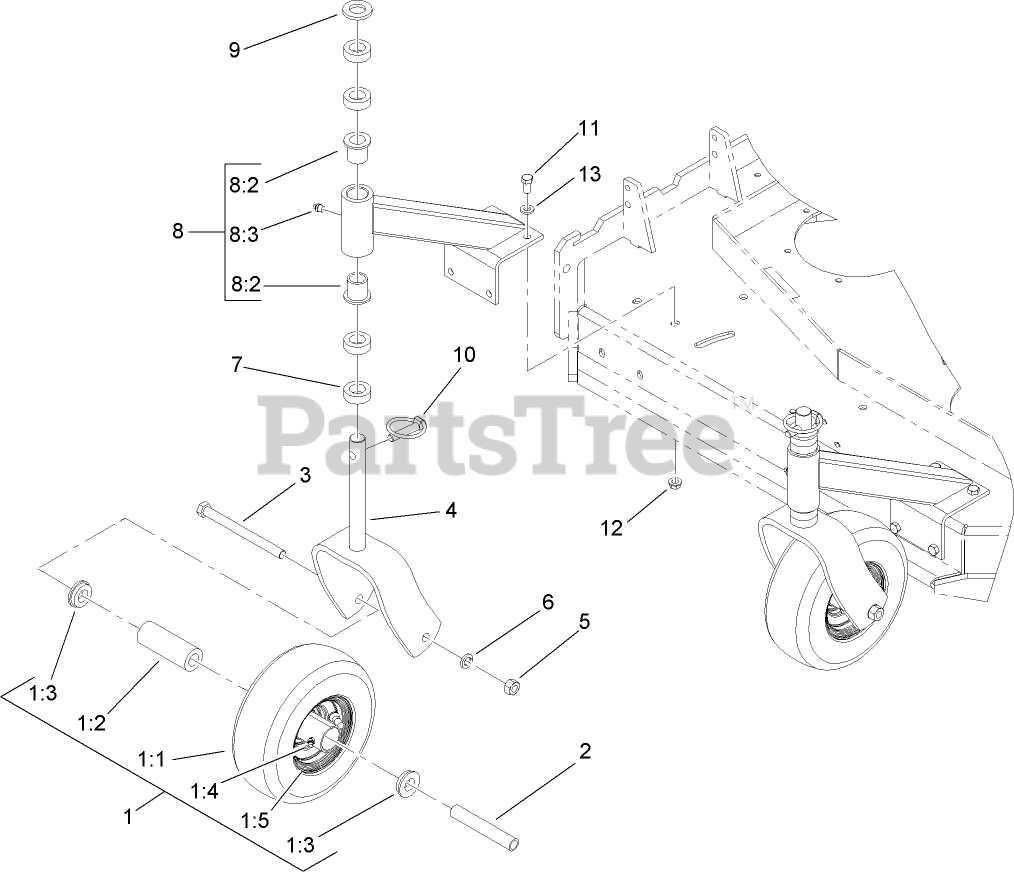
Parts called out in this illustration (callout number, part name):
1	WHEEL AND TIRE ASM
1:1	TIRE
1:2	BEARING
1:3	BUSHING
1:4	FITTING-GREASE
1:5	WHEEL
2	SPACER
3	SCREW-HH
4	FORK
5	NUT-HH
6	WASHER-LOCK
7	SPACER-CASTER
8	SUPPORT ASM
8:2	BEARING-FLANGED
8:3	FITTING-GREASE
9	WASHER-FLAT
11	SCREW-HH
12	NUT-HHF, WHIZ
13	WASHER-FLAT
